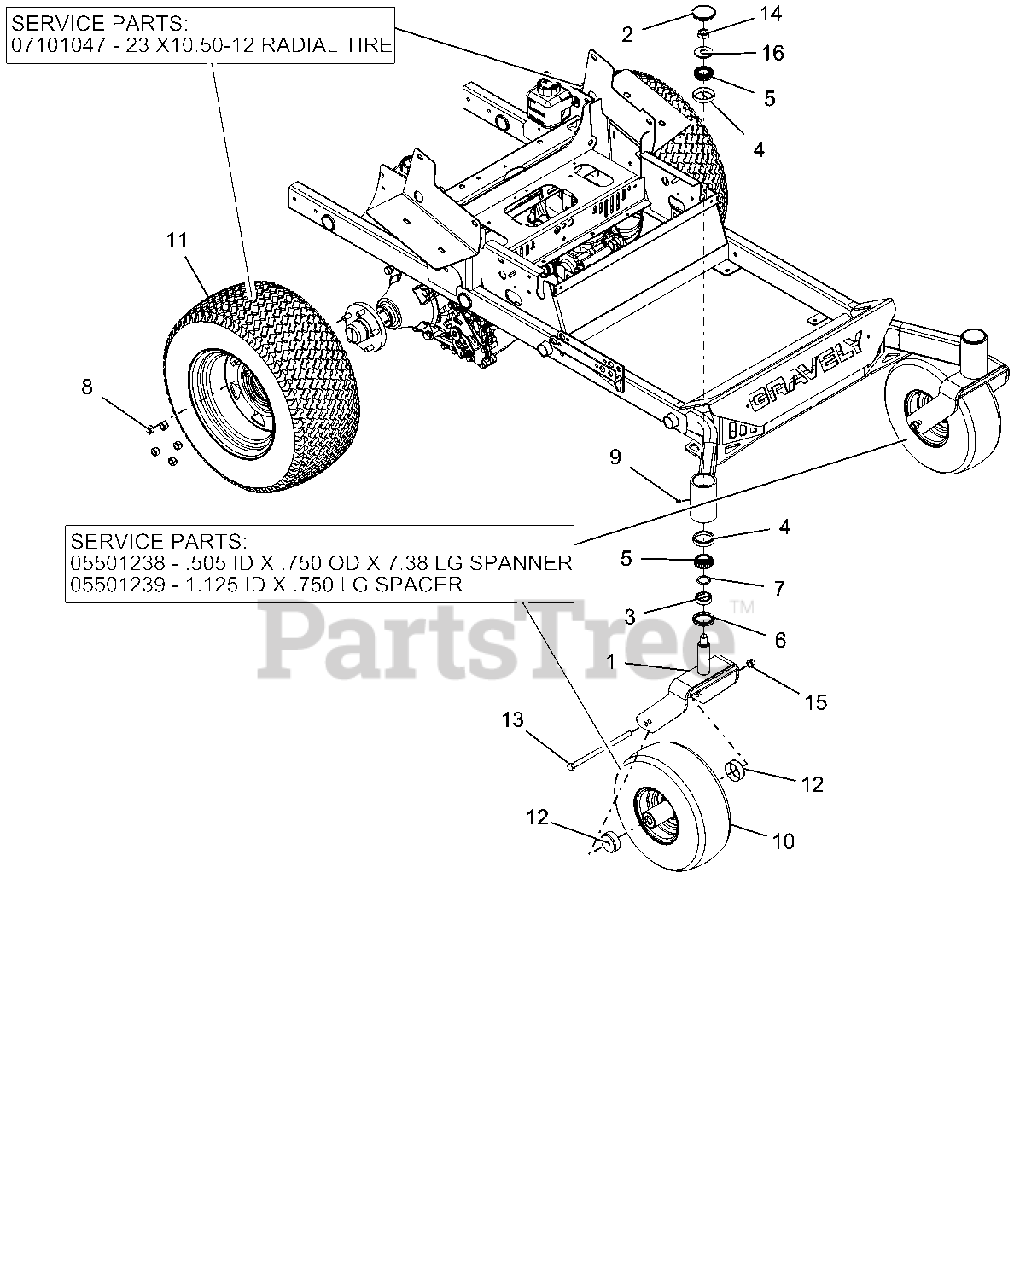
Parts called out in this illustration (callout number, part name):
1	CASTER FORK WMT - RED
2	CAP, DUST
3	SPCR, FRONT CASTER FORK
4	BRG-CUP 2.328X.465
5	BRG-CONE 1.25X.66
6	SEAL, OIL 1.75 X 2.332 X .312
8	WHEEL NUT .500-20 YZ
9	FTG, .25-28 FLUSH MNT GREASE
10	SPACER, 1.125 ID X .750 LG
10	SPANNER,.505ID X.750OD X7.38LG
10	ASM, WHL/TIRE 15X6.00-6 SEMI
11	TIRE, 23 X 10.50-12 RADIAL
11	ASM,WHL/TIRE 23X10.50-12RADIAL
12	SHIELD, WHEEL BEARING
13	@BLT-HEX .50-13X9.00 GR5 YWZC
14	NUT-JAM TOPLK .75-16 YWZC
15	NUT-LK-TOP-FLG .50-13 YWZC
16	@WSHR-FL-STL.812X2.00X.148YWZC
